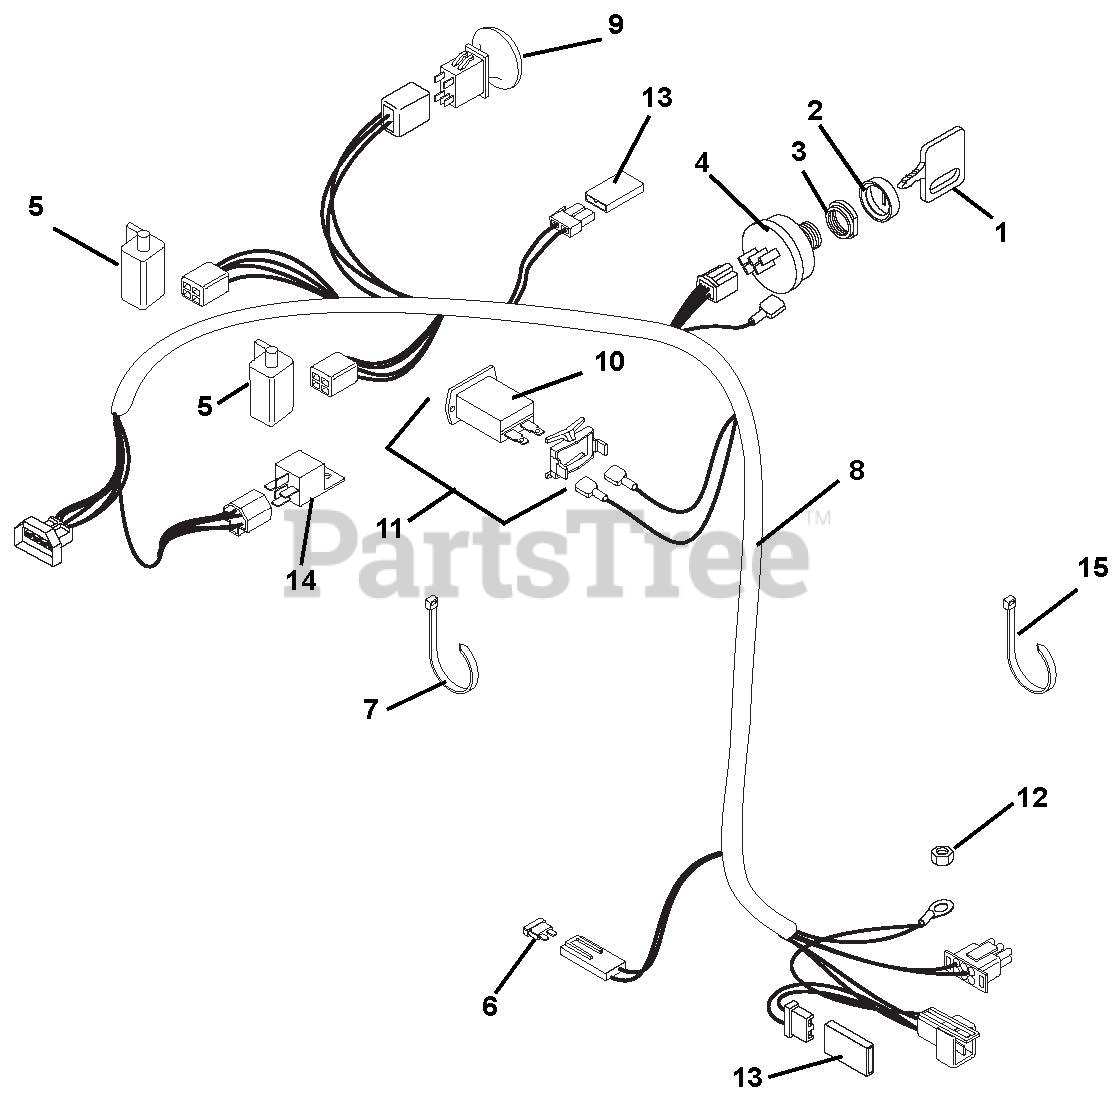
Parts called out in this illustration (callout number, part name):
1	Key- with Cap
2	Cap, Ignition Switch
3	Nut, Panel .562-24
4	Key Switch
5	Switch- Single Pole N.O.
6	Fuse-25 AMP
7	Tie Wrap-Black
8	Harness, Wire Gear Recoil-Pro Steer
9	Switch, Clutch
10	Hour Meter-Quartz
11	Kit, Hour Meter
12	Nut-Locking-Top-Flange .31-18
13	Diode, Connector Shell
14	Relay
15	Tie Wrap
